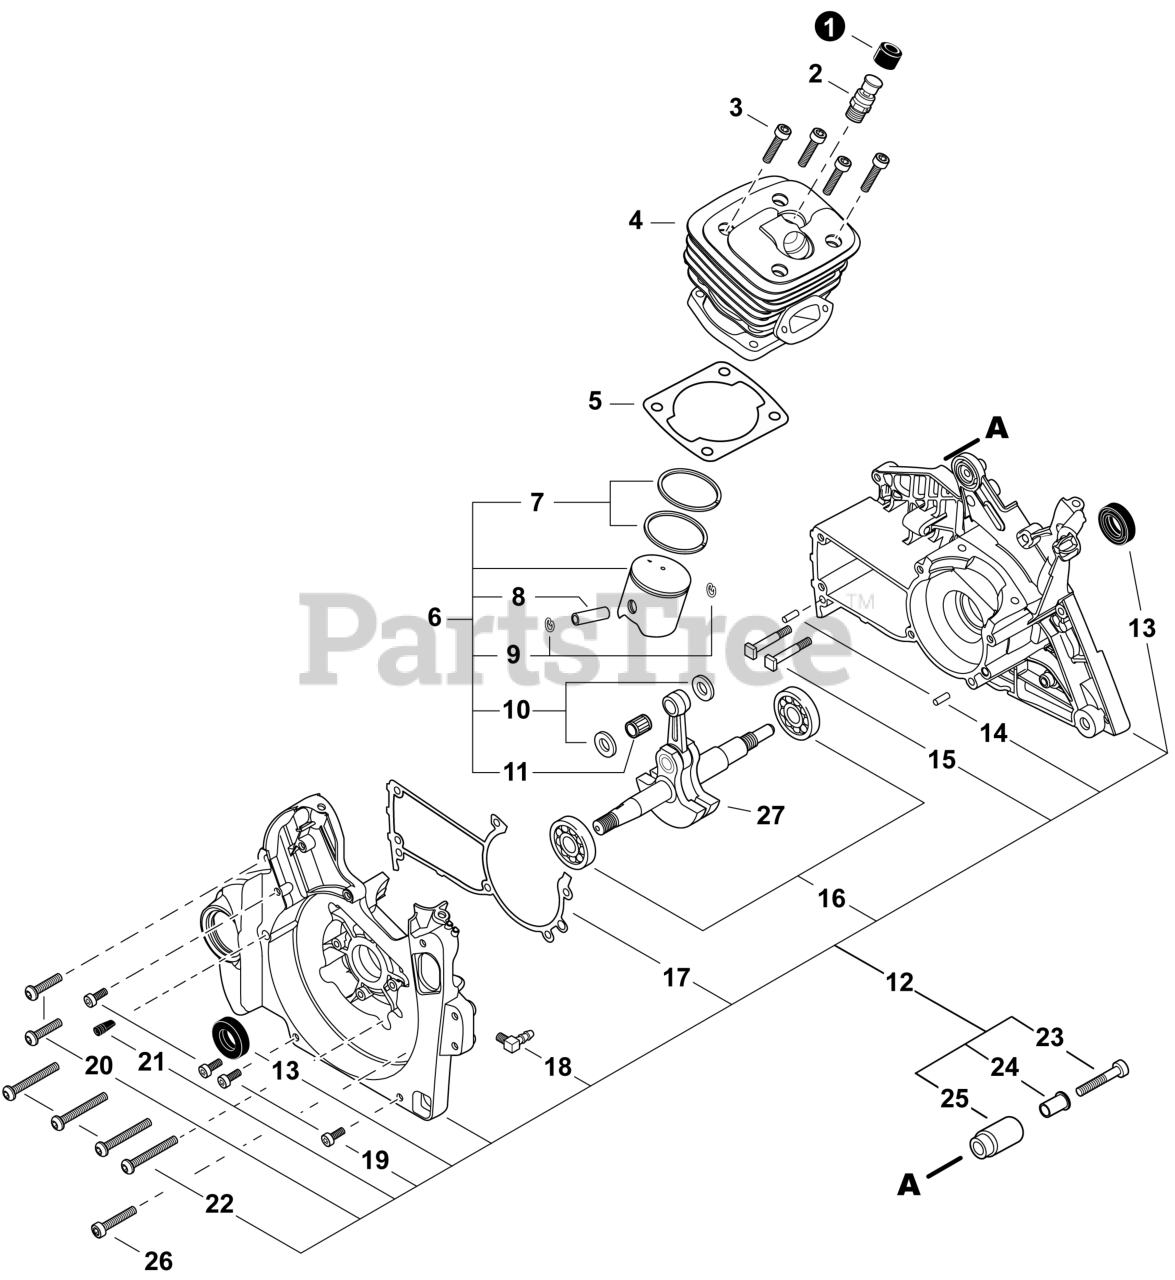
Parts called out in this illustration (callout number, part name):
1	COVER, DUST
2	VALVE ASSY, DECOMPRESSION
3	BOLT, TORX 5x25
4	CYLINDER
5	GASKET, CYLINDER
6	PISTON KIT
7	RING, PISTON
8	PIN, PISTON
9	RING, SNAP 11
10	WASHER, THRUST
11	BEARING, NEEDLE 11
12	CRANKCASE KIT
13	SEAL, OIL 15
14	PIN, LOCATING 5x10
15	STUD, GUIDE BAR 8
16	BEARING, BALL 6202
17	GASKET, CRANKCASE
18	CONNECTOR, PIPE
19	BOLT, TORX 5x20
20	BOLT, TORX 5x20
21	VENT ASSY
22	BOLT, TORX 5x35
23	BOLT, TORX 6x30
24	COLLAR 6
25	CATCHER, CHAIN
26	BOLT, TORX 5x25
27	CRANKSHAFT ASSY
